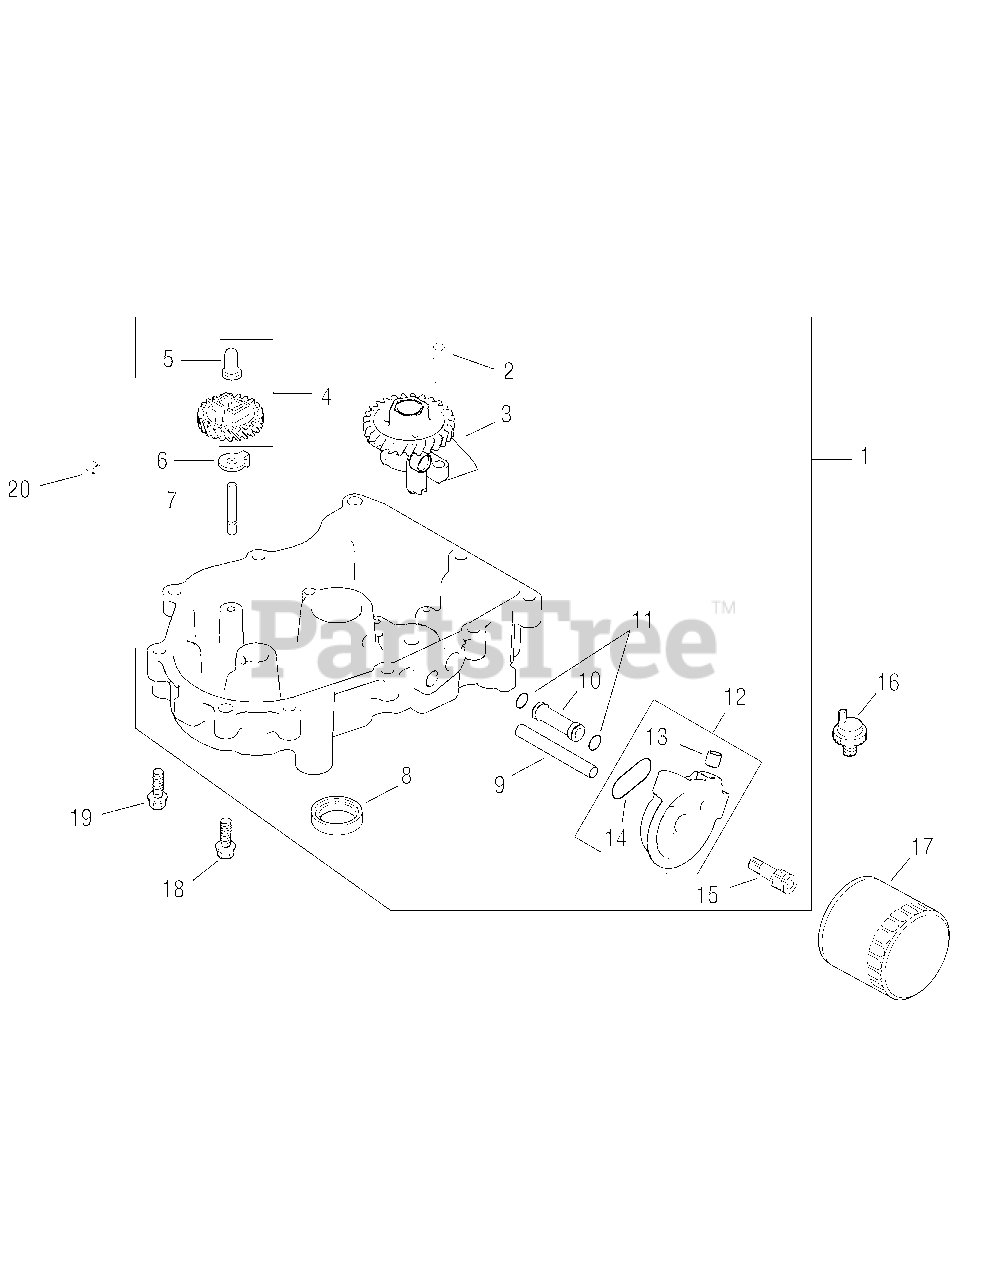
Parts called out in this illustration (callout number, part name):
1	Oil Pan Assembly (Inc. 2-15)
2	Hex Flange Screw
3	Oil Pump Assembly
4	Governor Gear Kit w/ Pin (Inc. 5)
5	Governor Regulating Pin
7	Governor Gear Shaft
8	Oil Seal (PTO End)
9	Oil Feed Tube - Filter To Oil Pan
10	Oil Feed Tube - Oil Pan To Filter
12	Oil Filter Adapter (Inc. 13 & 14)
13	Hex Ctsk. Plug, 1.8
14	Oil Filter Adapter O-Ring
15	Oil Filter Nipple
16	Pressure Switch
18	Hex Flange Screw, M8 x 1.25 x 45
19	Hex Flange Screw, M8 x 1.25 x 45
20	Sq. Hd. Solid Plug, 3.8
